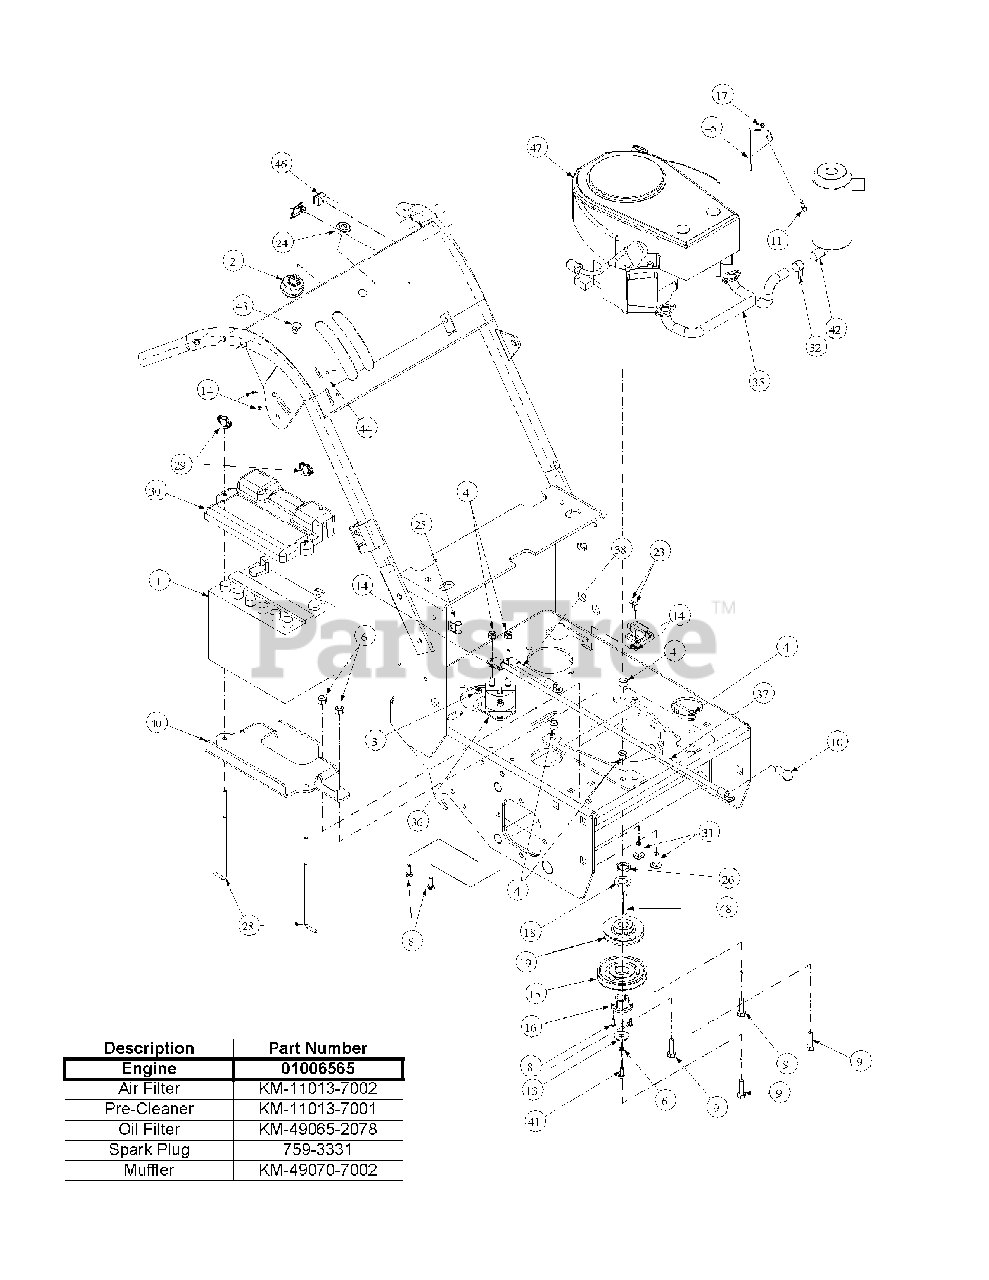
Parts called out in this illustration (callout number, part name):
1	Battery 12V
2	Ignition Switch
3	Lock Nut Nylon Insert, 1/4-20
4	Nylock Nut, 5/16-18
5	Nylock Nut, 3/8-16
6	Lock Washer, 7/16
7	Delta Switch
8	Hex Cap Screw, 1/4-20, .75
9	Hex Cap Screw, 5/16-18 x 2
10	Rubber Boot, 1" OD
11	Hex Cap Screw, 5/16-18 x 3/4
12	Screw, Hex Washer w/slot, 10-32x1/2
13	Clutch Washer
14	Lock Nut, Nylon Insert, #10-32
15	Deck Pulley
17	Lock Nut, 5/16-18
18	Washer
19	Sheave, 1" Bore with 2 Set Screws
20	Retainer Clip
21	Black Battery Cable, 17" Long
22	Harness Wire
23	Machine Screw, 10 -32 x 5/8
24	Nut w/cap 5/8-32
25	Support Clamp 3/8 OD
26	Engine Pulley Spacer, 12.5
28	Battery Holdown Rod
29	Wing Nut, 1/4-20 w/Bell Washer
30	Battery Cover
31	Carriage Bolt, 3/8-16 x 1
32	Muffler Clamp Assembly
34	Harness Hourmeter
36	Magnetic Solenoid Switch
37	24" Red Battery Cable
38	5" Red Battery Cable
39	Harness Adapter Kawasaki
40	Battery Bracket
41	Capscrew, 7/16-20 x 1-1/4
43	Cable Choke
44	Control Throttle w/Detent
45	Muffler Bracket
46	Hour Meter
47	17 HP Kawasaki Engine
48	Key Stock, 1/4 x 1/4 x 2.75
